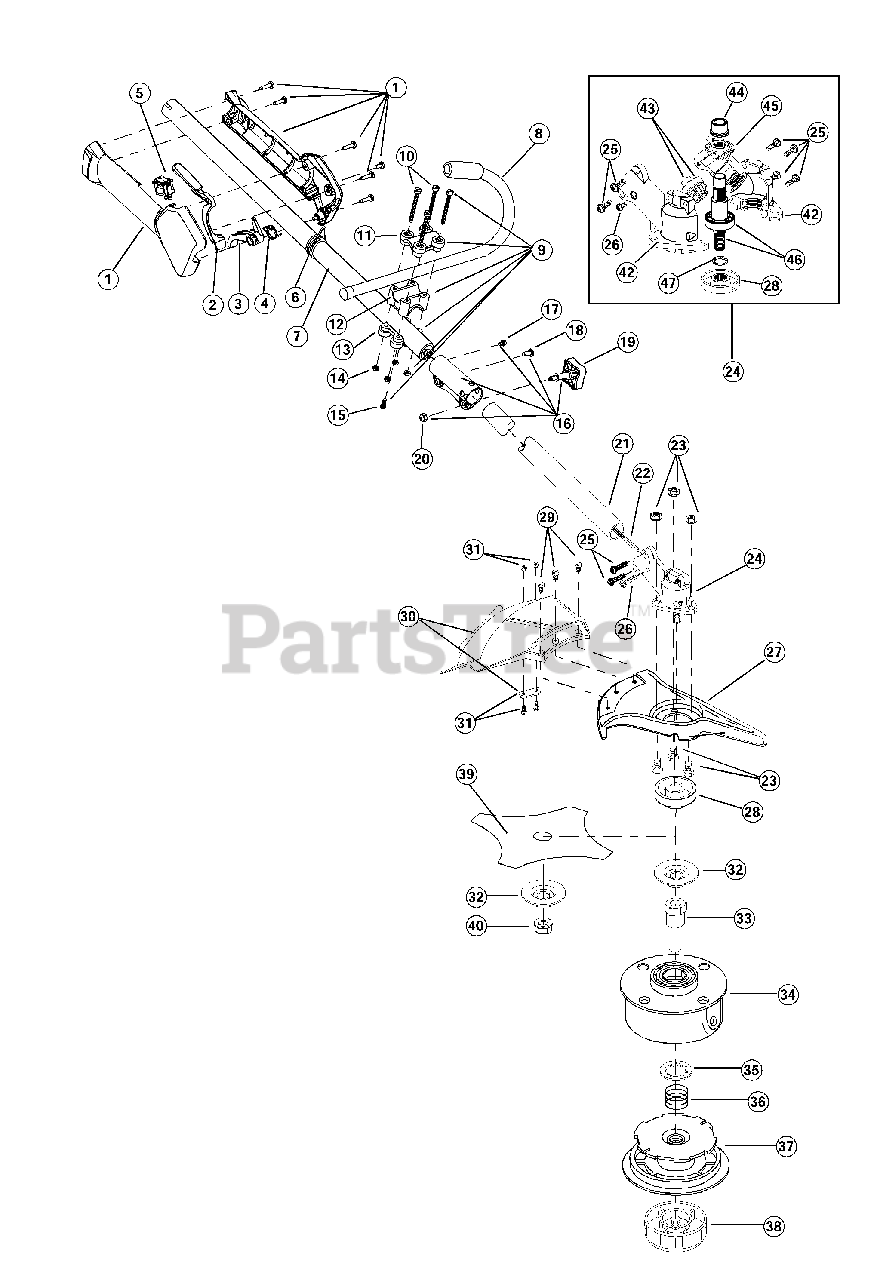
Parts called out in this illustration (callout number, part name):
1	Throttle Housing and Trigger Assembly
2	Throttle Trigger Lock-Out
3	Throttle Trigger
4	Throttle Trigger Spring
5	Switch Assembly
6	Harness Clip
7	Upper Drive Shaft Housing Assembly
8	J-Handle Assembly
9	Handle Bracket Assembly
11	Upper Handle Clamp
12	Middle Handle Clamp
13	Lower Handle Clamp
15	Anti-Rotation Screw
16	EZ-Link Coupler
19	Adjustment Knob
20	Knob Retaining Nut
21	Lower Drive Shaft Housing Assembly
22	Lower Flexible Drive Shaft
23	Shield Mount Screw Assembly
24	2 piece Gearbox Assembly
25	Gearbox Screw
26	Anti-Rotation Screw
27	Blade Shield/Shield Mount
28	Blade Driver
29	Shield Mounting Screw
30	Shield and Blade Assembly
31	Blade Assembly
32	Retaining Washer
33	Spool Shaft
34	Outer Spool and Eyelet Assembly
35	Retainer
38	Bump Head Knob Assembly
39	4-Tooth Blade
40	Nut
41	Left Housing
42	Right Housing
43	Pinion Gear Assembly
44	Output Shaft Bushing
45	Output Shaft Gear
46	Output Shaft Assembly
47	O-Ring
